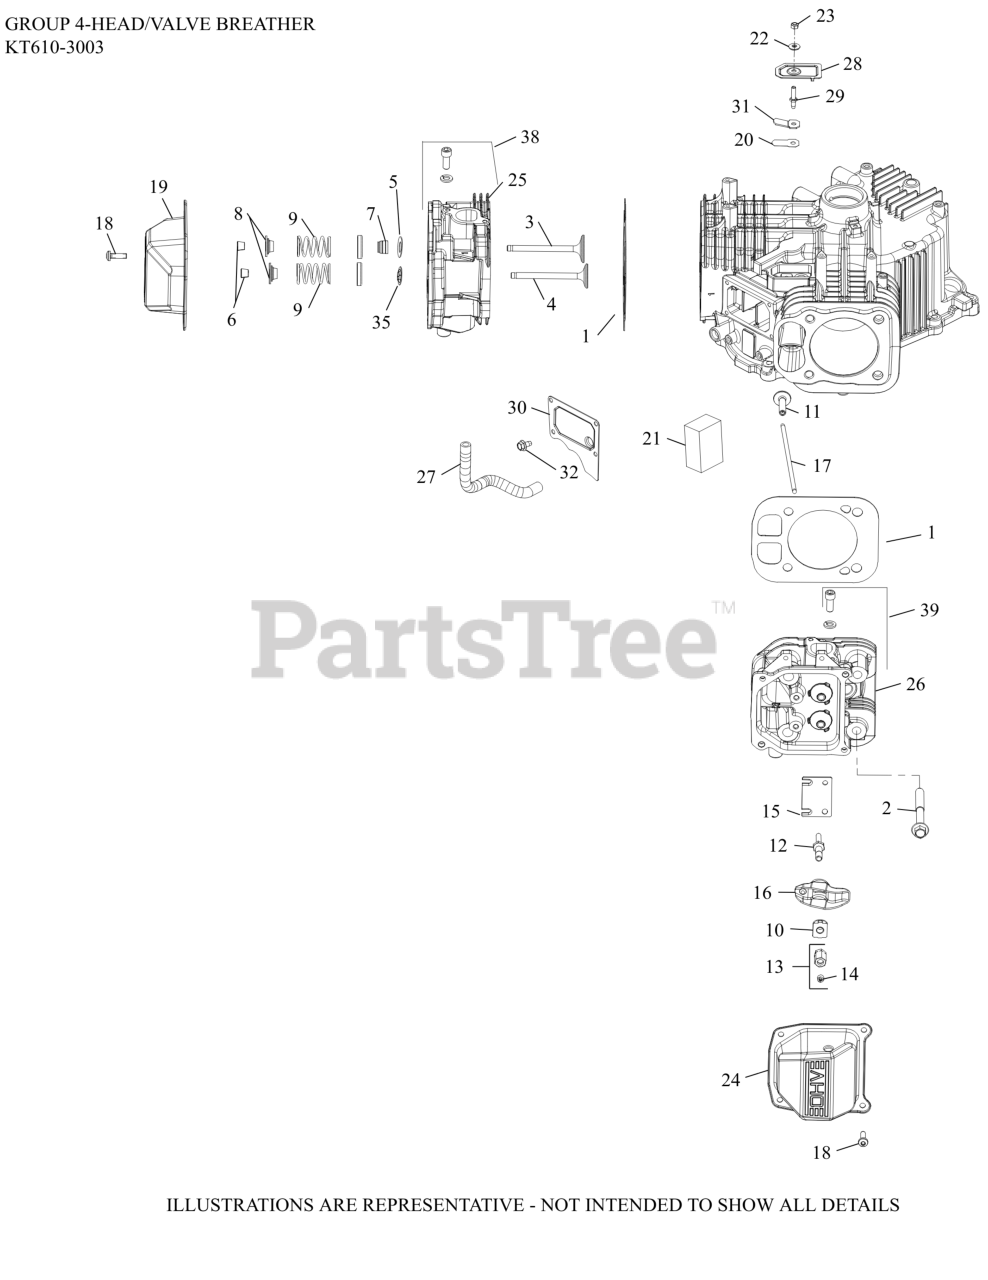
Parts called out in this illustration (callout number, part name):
1	KIT, CYLINDER HEAD GASKET
2	SCREW, FLG M10X1.5X90
3	VALVE, INTAKE
3	VALVE, INTAKE (.25) - (#2401702S)
4	VALVE, EXHAUST
4	VALVE, EXHAUST (.25)
5	SPACER (.010")
6	KIT, RETAINER
7	SEAL, VALVE BAND
8	CAP, VALVE SPRING
9	SPRING VALVE
10	PIVOT, ROCKER ARM
12	STUD, ROCKER
13	HEX NUT ASSEMBLY
14	SCREW, SET
15	PLATE, GUIDE
16	ARM, ROCKER
17	ROD, PUSH
18	SCREW, PAN HEAD
19	COVER, ROCKER STAMPED STEEL
20	REED, BREATHER
21	FILTER, BREATHER
22	WASHER, SEALING
23	NUT, LOCK M5X.8
24	COVER, ROCKER STAMPED STEEL
25	HEAD, ASSY CYL (#1)-USE 32 755 29-S
26	HEAD, ASSY CYL (#2)-(#3275530S)
27	HOSE, BREATHER
28	COVER, BREATHER REED
30	COVER, BREATHER MEDIA
31	RETAINER, REED
32	SCREW, THREAD FORMING
35	RETAINER, VALVE GUIDE (KM)
38	KIT, #1 HEAD AND HARDWARE-(#3275539S)
39	KIT, #2 HEAD AND HARDWARE-(#3275540S)
